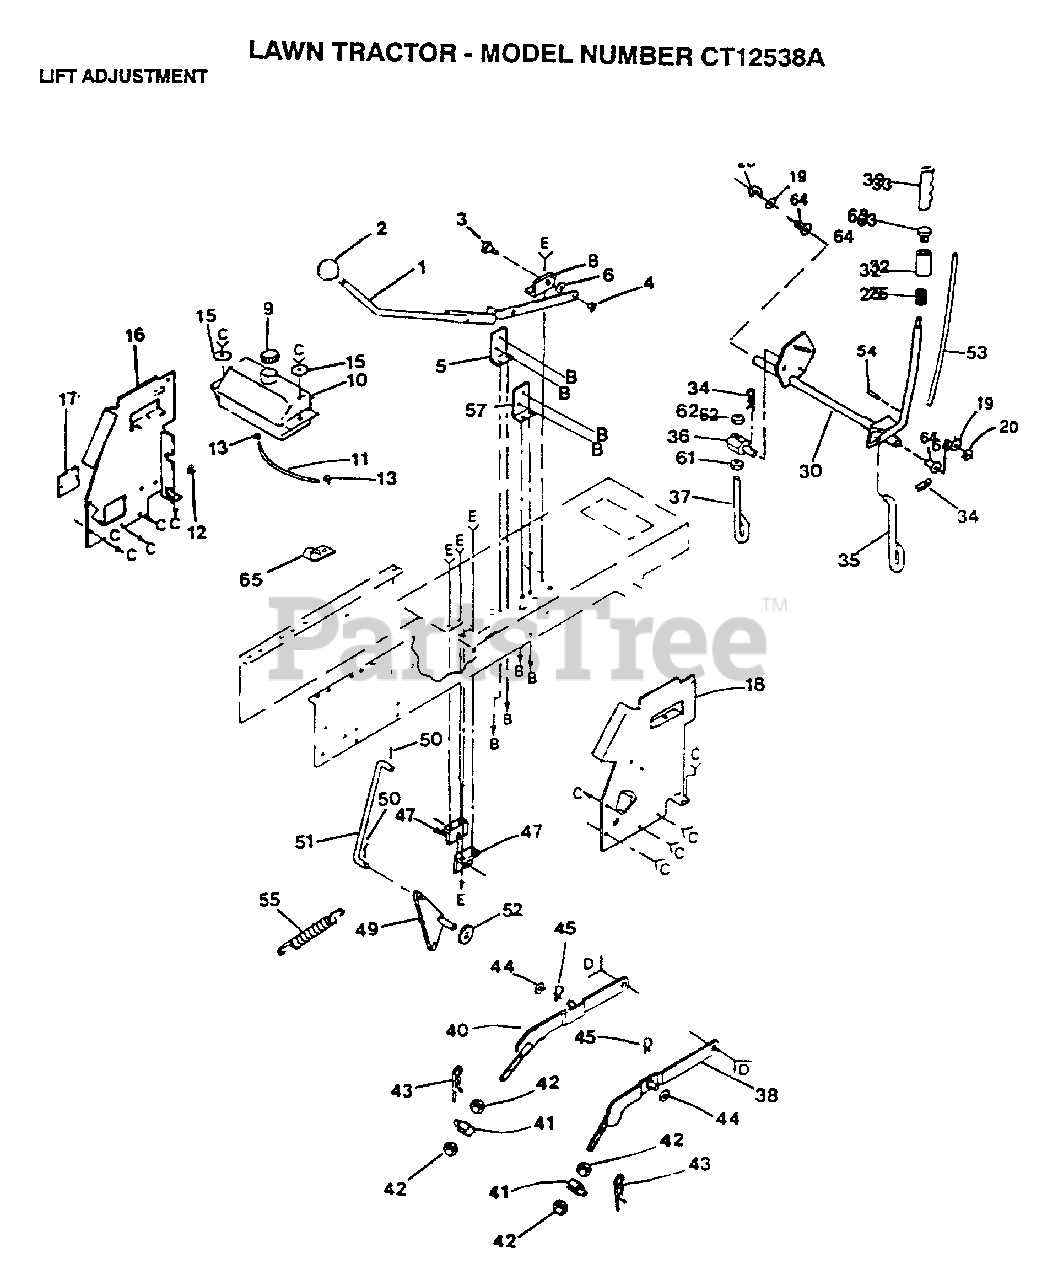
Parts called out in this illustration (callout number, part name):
3	"BOLT, SHOULDER LT"
5	"BRACKET,SWITCH LT"
8	"SUP,LVR,CLUTCH LT"
10	TANK.FUEL.LT.
11	FUEL LINE T
12	SNAP BUSHING T
13	HOSE CLAMP
15	WASHER GT
16	PANEL DASH LH
17	COVER ACCESS
19	WASHER
33	GRIP
35	LIFT LINK LT
37	PIVOT PIN T
38	RH SUSP ARM ASM
40	LH SUSP ARM ASM
42	NUT
43	SPRING H
45	SPRING.RETAINER
47	"BRKT,BELLCRAN T"
49	"T, BELLCRANK"
50	COTTER PIN
52	WASHER
54	PIN-GROOVE LT
57	BRACKET LT
61	NUT
64	NYLON BEARING
65	INSUL CLIP T
